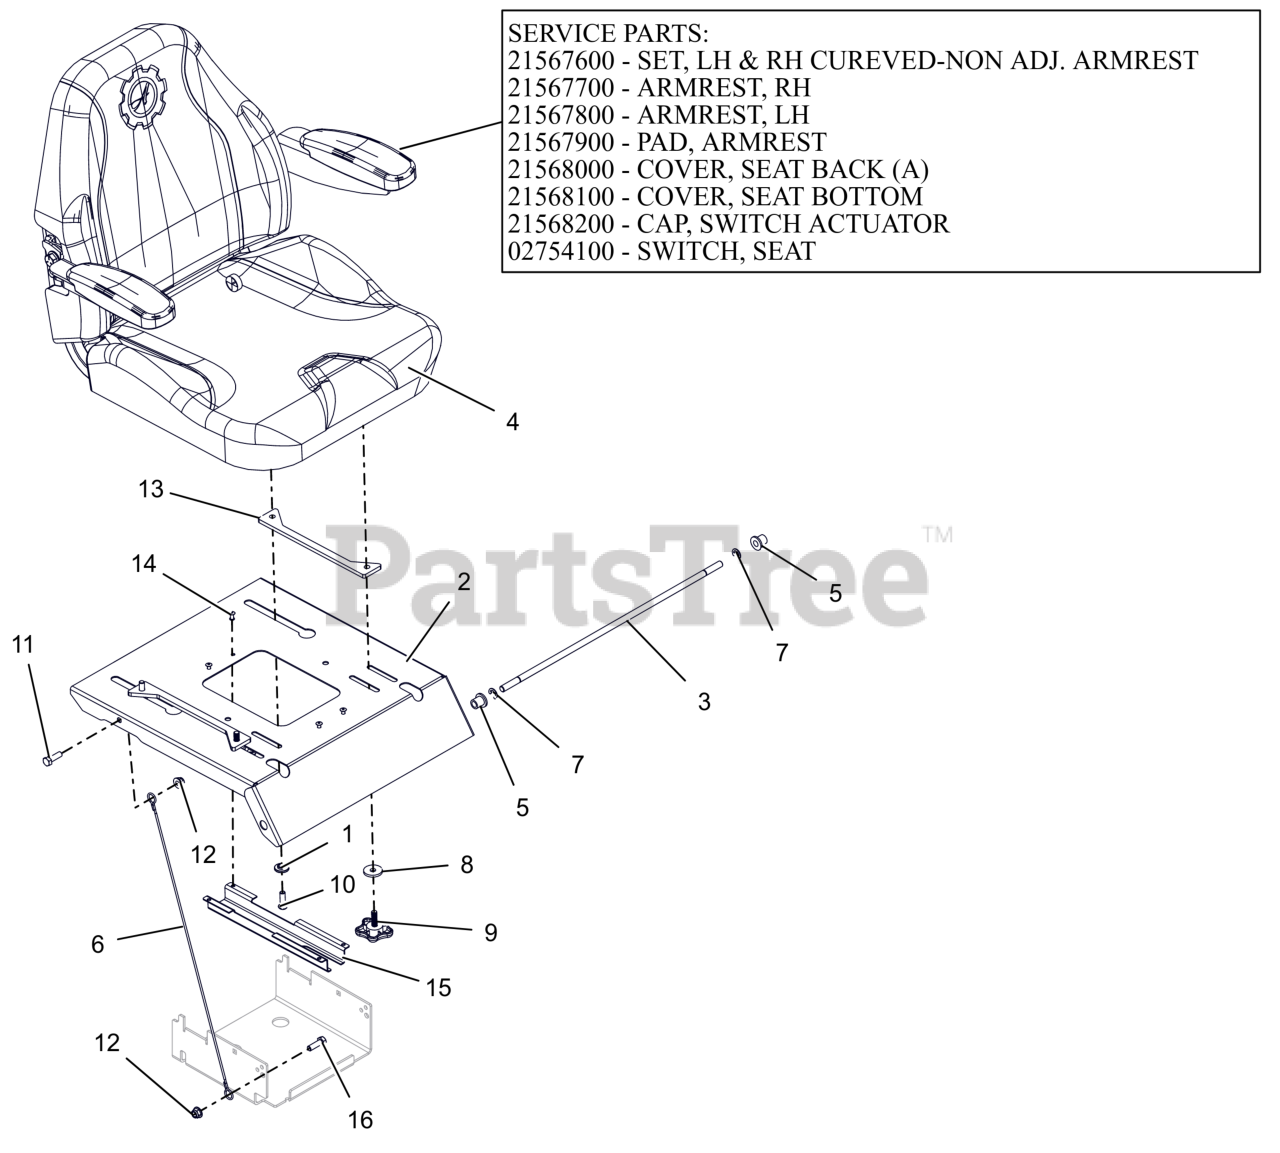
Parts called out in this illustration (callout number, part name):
1	BSHG, FLG .312X.499X.23X.88
2	PLATE, SEAT (ORANGE)
3	ROD, SEAT PIVOT
4	SEAT, -IKON
4	SET,LH&RG CURVED-ARMREST
4	ARMREST-CURVED RH
4	ARMREST-CURVED LH
4	PAD, ARMREST (BLACK SELFSKIN)
4	COVER, SEAT BACK (A)
4	COVER, SEAT BOTTOM (A)
4	CAP, SWITCH ACTUATOR
4	SWITCH- SNAP MTG N.O.
5	BSHG-FLG .38X.580X.667X.750
6	LANYARD, SEAT CABLE .093X19.5
7	RG-RTNG-EXT .375X.035 TYP E
8	WSHR, FLT .340X1.125X.135 ZCC
9	KNOB, WING STUDDED
10	BLT,SHCS-BTN .31-18X1.00 ZCC
11	BLT,HEX .31-18X1.00 G5 ZCC
12	NUT,LK-NYL-FLG .31-18 G5ZC120
13	SPCR, SEAT SLIDE (BLACK)
14	RVT-POP.187X.527 DOME ST
15	GUARD, SEAT SWITCH
16	BLT,HEX .31-18X1.00 G5 ZCC
